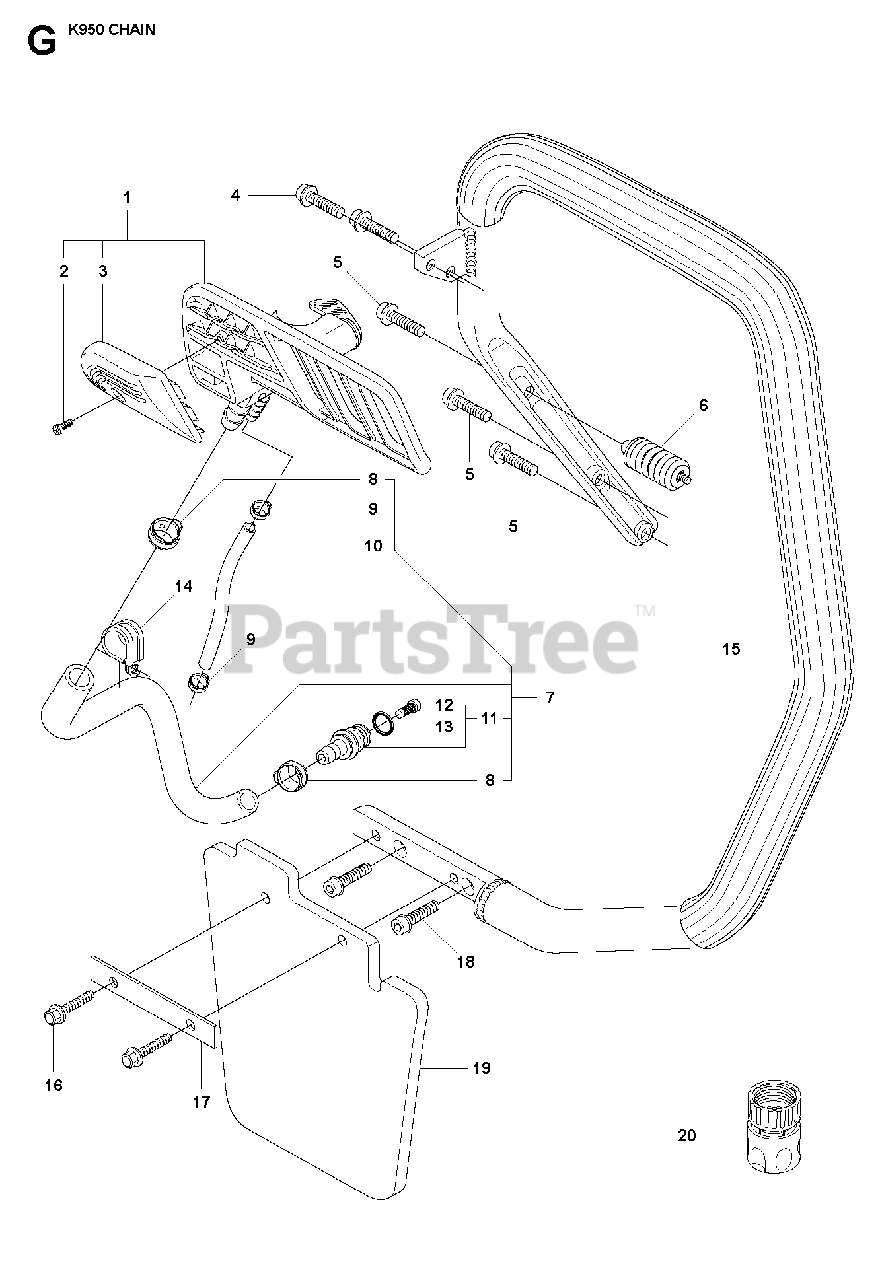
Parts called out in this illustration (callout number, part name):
2	SCREW CCRPANT
4	SCREW IHSCFT
6	ANTIVIBRATION ELEMENT
7	HOSE KITIncl. 8, 9, 10, 11, 14
8	HOSE CLAMP
11	NIPPLEIncl. 12, 13
13	O-RING
20	COUPLER
